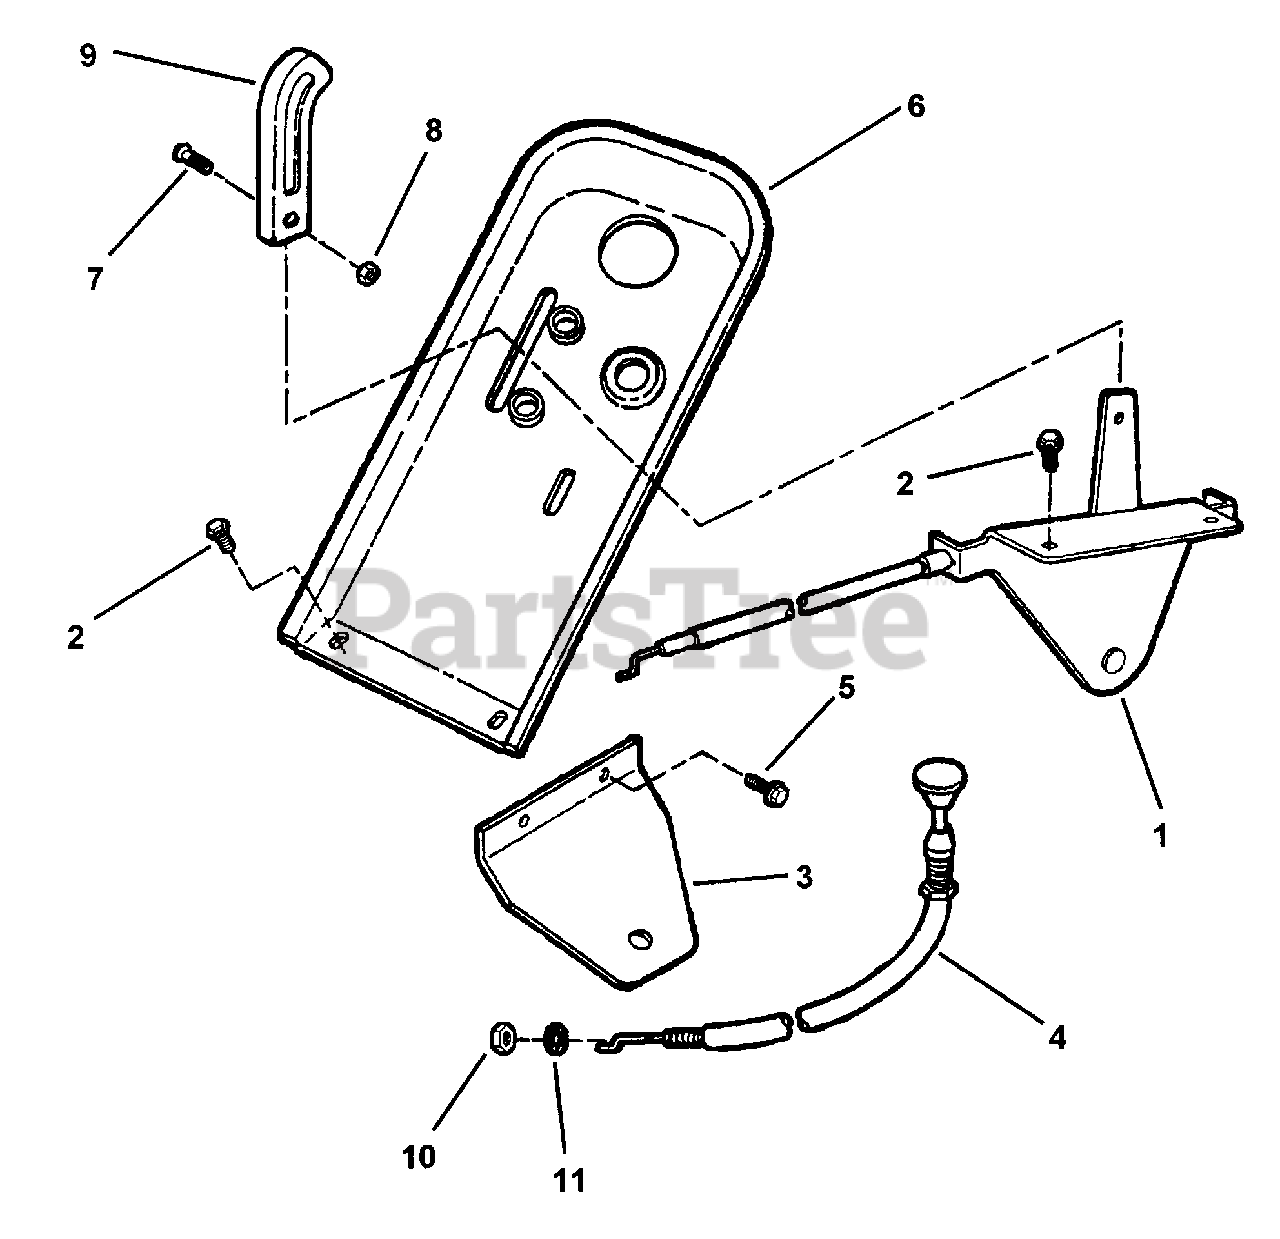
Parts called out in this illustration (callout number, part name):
1	CONTROL, Throttle
2	SCREW, #10-24 x 1/2" Hex Washer Self-Tap (Torx)
3	PLATE, Throttle Control
4	CONTROL, Choke
5	SCREW, 1/4-20 x 5/8" Self-Tap
6	COVER, Dash Panel
7	SCREW, #8-32 x 3/8" Cross-Recess, Fillister Head
8	NUT, #8-32 Hex
9	KNOB, Throttle Control
10	NUT, 3/8-24 Hex
11	WASHER, 3/8" Internal Tooth Lock
